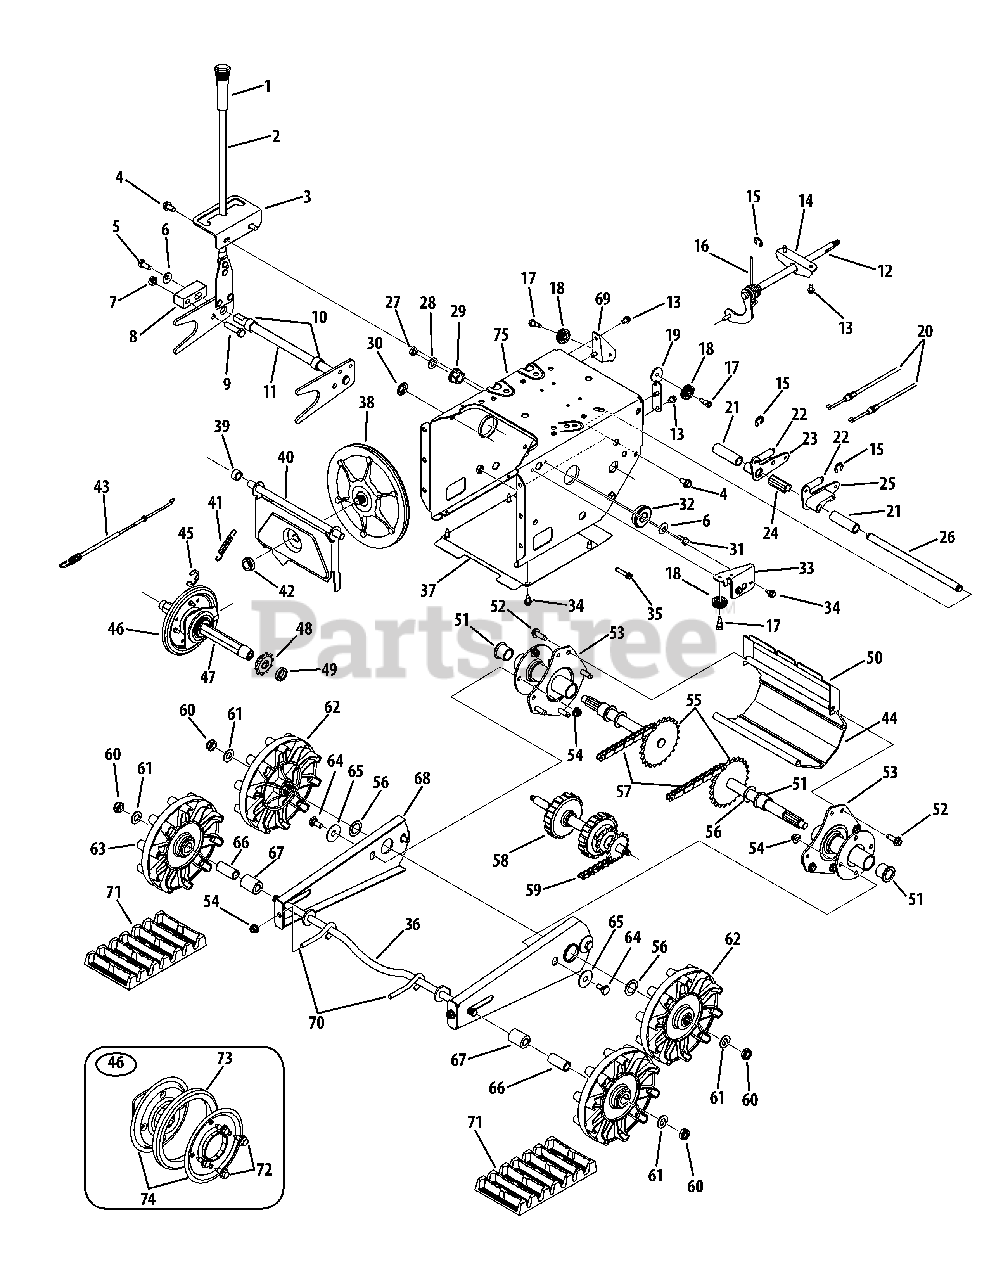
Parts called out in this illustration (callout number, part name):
1	Grip, .5 ID x 3.45
2	Track Lock Handle Assembly
3	Lockout Track Bracket Plate
4	Hex Washer Screw, 5/16-18 x .750
5	Hex Screw, 5/16-24 x .75
6	Bell Washer, .340 x .872 x .060
7	Hex Lock Nut, 3/8-16
8	Lift Shaft Drive
9	Hex Screw, 3/8-16 x 1.50
10	Spacer, .828 ID x .875 OD x .500
11	Pivot Rod Assembly
12	Shift Rod Assembly
13	Hex Washer Screw, 1/4-20 x .500
14	Shift Frame Bracket
16	Torsion Spring, .750 ID x .968
17	Shoulder Screw, .34 x .335 x 1/4-28
18	Cable Roller
19	Auger Cable Guide Bracket
20	Track Steering Cable
21	Spacer, .515 x 735 x 2.44
22	Extension Spring, .48 OD x 2.03
23	Dogg Assembly, RH
24	Spacer, .491 ID x 1.87
25	Dogg Assembly, LH
26	Shift Actuator
27	Jam Lock Nut, 3/8-24
28	Flat Washer, .406 x .875 x .059
29	Hex Flange Bearing
30	Speed Nut, .500
31	Hex Lock Screw, 5/16-18 x .625
32	Ball Bearing
33	Auger Cable Support Guide
34	Hex Washer Screw, 1/4-20 x .625
35	Hex Washer Screw, 1/4-20 x 1.000
37	Track Frame Cover
38	Friction Wheel Disc Assembly
39	Spacer, .525 ID x .750 x .42
40	Friction Wheel Support Bracket
41	Extension Spring
42	Flange Nut, 5/16-18
43	Drive Clutch Cable
46	Friction Wheel Assembly
47	Hex Track Shaft
48	Sprocket, 10T
49	Spacer, .675 ID x 1.00 OD x .23
50	Steering Cable Bracket
51	Flange Bearing
52	Hex Washer Screw, 5/16-18 x 1.0
53	Track Hub Assembly
54	Flange Lock Nut, 5/16-18
55	Track Axle Assembly
56	Flat Washer, .793 x 1.24 x .06
58	Drive Track Shift Assembly
60	Jam Lock Nut, 1/2-20
61	Flat Washer, .510 x 1.00 x .060
62	Track Drive Wheel
63	Track Idler Wheel
64	Shoulder Screw, .43 x .56 5/16-18
65	Flat Washer, .442 x 1.38 x .060
66	Spacer, .51 ID x .75 OD x 1.67
67	Spacer, .510 ID x 1.0 OD x 1.34
69	Drive Cable Guide Bracket
70	Eye Bolt, 5/16-18 x 3.0
71	Snow Trac
72	Hex Washer Screw, 1/4-14 x .625
73	Friction Wheel
74	Friction Plate
75	Frame Assembly
